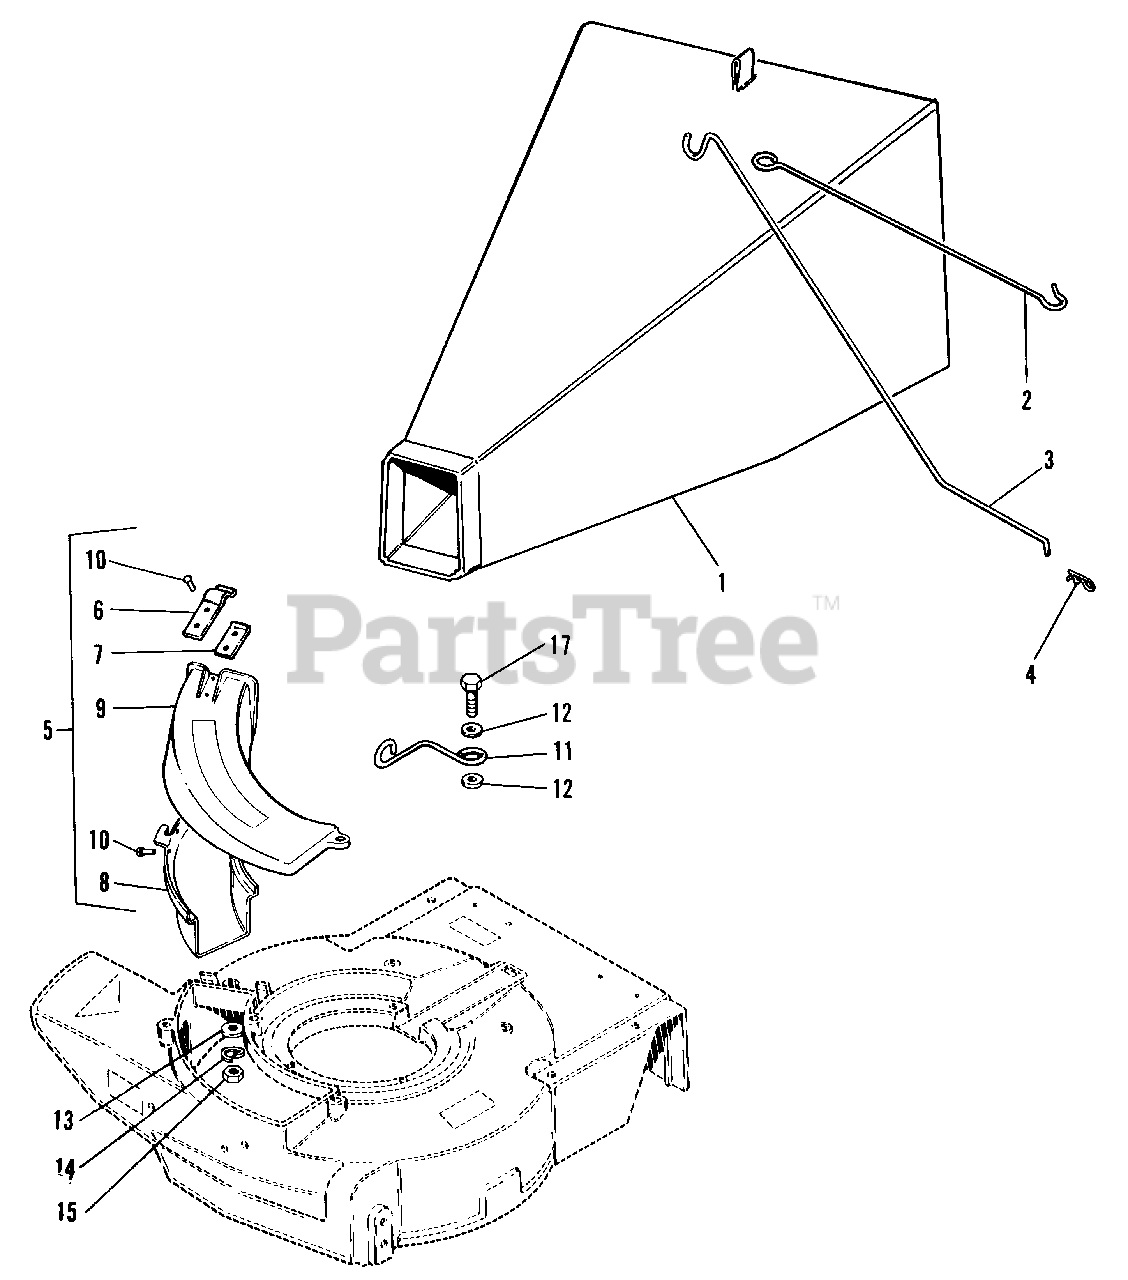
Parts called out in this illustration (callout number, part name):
2	HANGER, Leaf Bag
3	SUPPORT ROD, Bag
4	PIN, Quick, 1/8
5	CHUTE ASSY
6	LATCH, Spring
7	PLATE, Latch
8	DEFLECTOR
10	RIVET, Tubular, 3/8 x 5/16
11	GUARD, Bag
12	WASHER, Plain
14	LOCKWASHER
15	NUT, 1/4-20
16	DECAL, Caution
17	CAPSCREW, Hex Hd., 1/4-20 x 1
